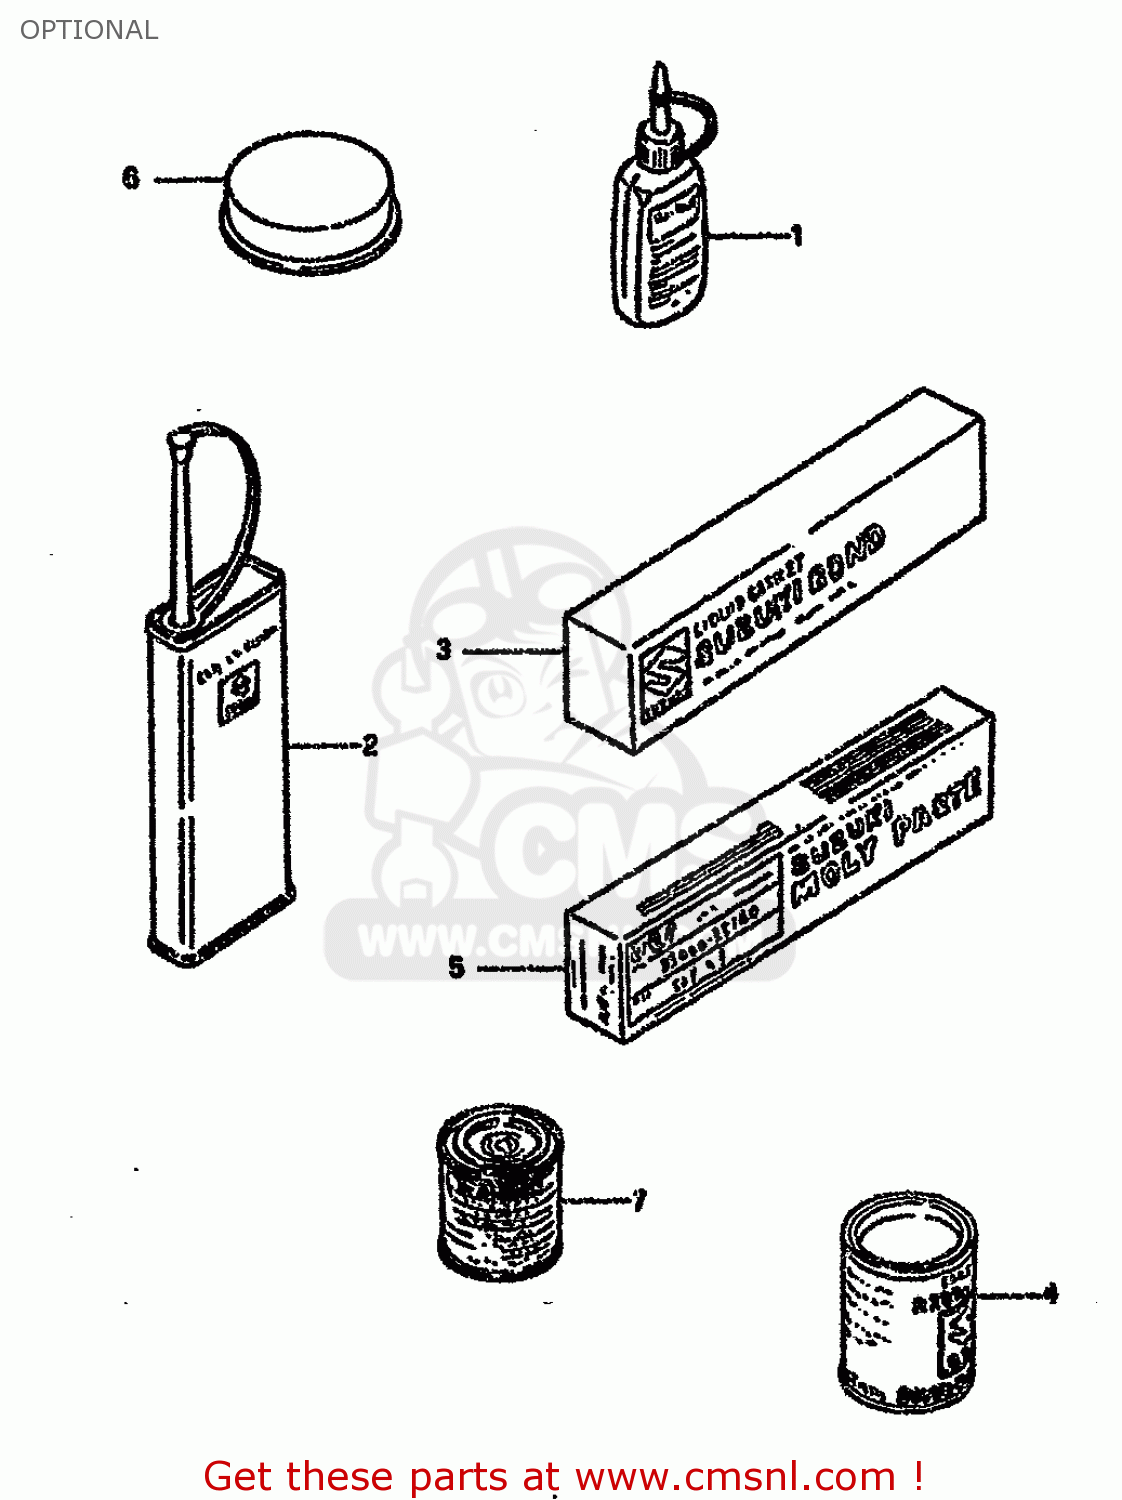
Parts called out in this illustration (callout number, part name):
1	THREAD LOCK NO.1342
2	THREAD LOCK NO.1401 CLEAR 200G
3	LIQUID GSKT NO.1207B 100G BLK
4	GREASE(C)EP2 LITHIUM 150G
5	SUZUKI MOLY PASTE
6	GREASE,PBC FOR BRK PAD 20G
7	PAINT (CANDY ALPINE BLUE)
